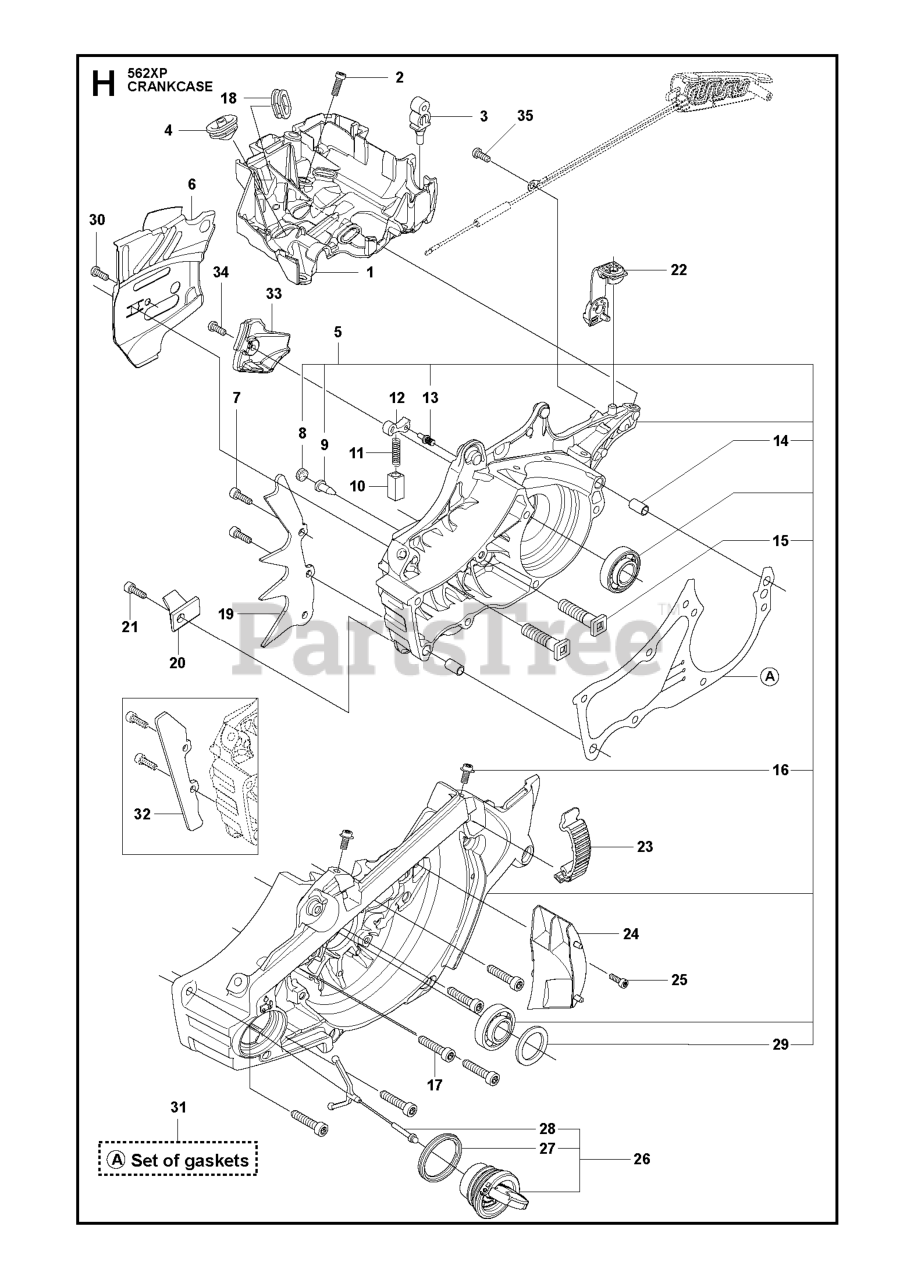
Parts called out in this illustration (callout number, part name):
1	CARBURETTOR AREA BASE
2	SCREW ITXSCFM
5	CRANKCASE ASSY
6	CHAIN GUIDE PLATE
7	SCREW ITXPANM M5X16 T27 10.9
8	PLUG
9	VALVE-CHECK (DUCKBILL)
11	LOCK SPRING
16	SCREW ITXSCM WASHER M5X12 T27
17	SCREW ITXSCM M5X25 12.9 TBO T
20	CHAIN CATCHER
22	DEFLECTION LIMITER
23	CLIP GRAY
24	AIR NOZZLE
25	SCREW ITXSCM M4X15 T27 12.9 T
26	TANK CAP ASSY
29	RADIAL SEAL
30	SCREW CITXPANT
31	GASKET KIT
33	CHAIN GUIDE
34	SCREW CITXPANT
